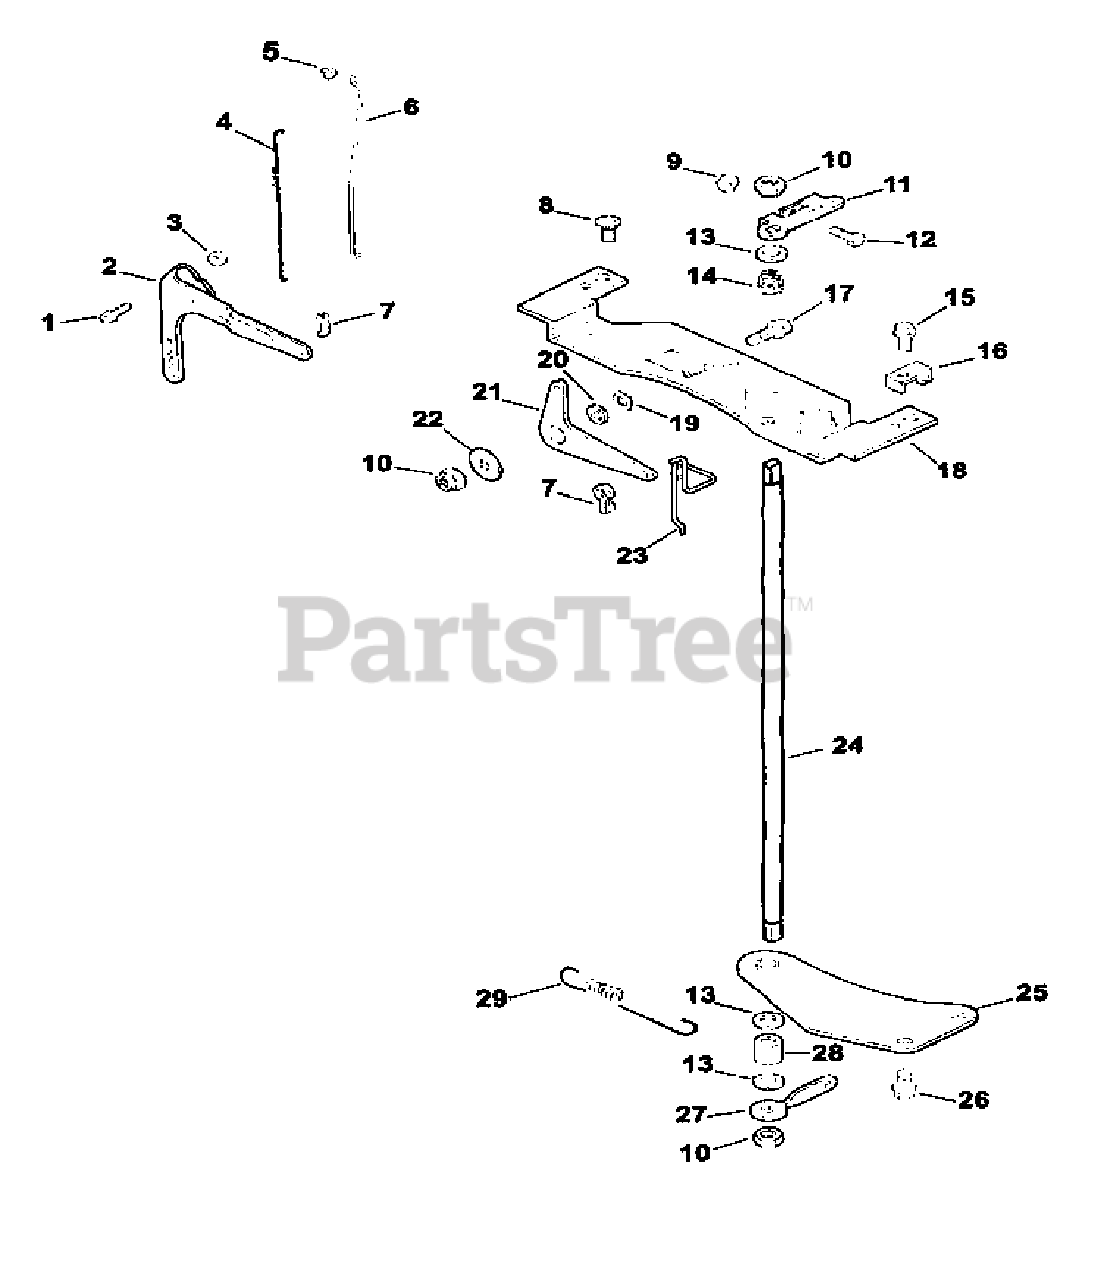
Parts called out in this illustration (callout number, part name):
1	Carriage Bolt (M6 x 1.0 x 25)
2	Governor Lever
3	Hex Flange Nut (M6 x 1.0)
4	Linkage Spring
5	Linkage Retaining Bushing
6	Throttle Linkage
7	Throttle Linkage Bushing
8	Phillips Head Screw (11-16 x 3/4")
9	Hex Nut (M4 x .7)
10	Hex Lock Nut (M6 x 1.0)
11	Throttle Control Lever
12	Hex Cap Screw (M4 x .7 x 25)
13	Plain Washer (1/4")
14	Throttle Shaft Spring
15	Hex Flange Screw (M5 x .8 x 16)
16	Cable Clamp
17	Hex Flange Screw (M6 x 1.0 x 16)
18	Control Bracket
19	Spring Washer (3/8")
22	Plain Washer (1/4")
23	Choke Linkage
24	Throttle Shaft
25	Throttle Shaft Bracket
26	Hex Flange Screw (M6 x 1.0 x 40)
27	Throttle Control Lever
29	Governor Spring
